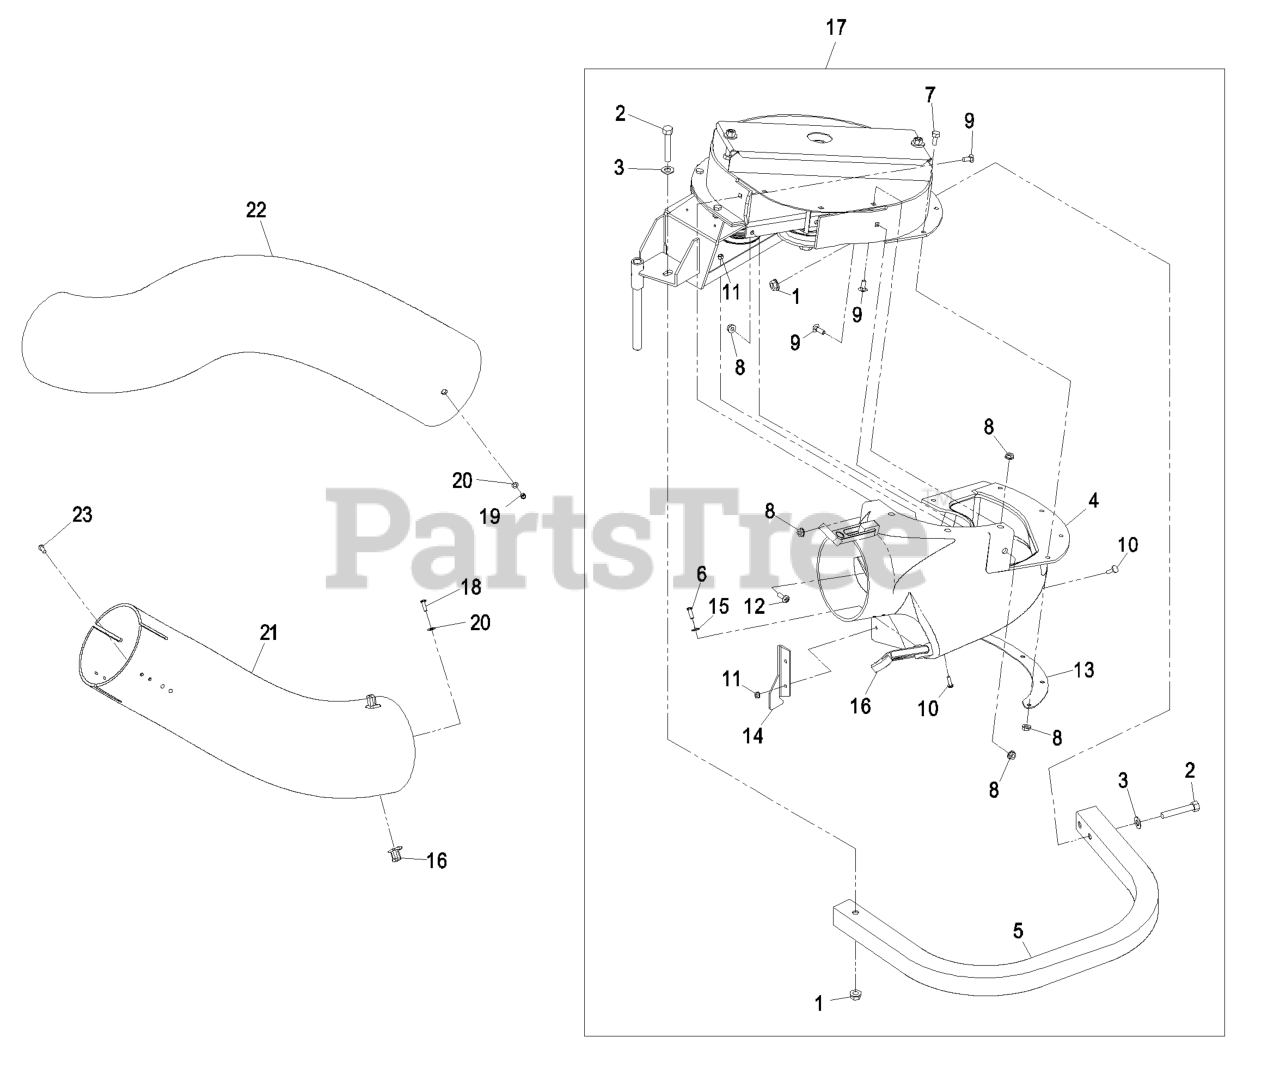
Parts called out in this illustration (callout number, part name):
1	NUT-HHF, WHIZ
2	SCREW-HH
3	WASHER-FLAT
4	ASM,BLOWER CHUTE SMALL
6	SCREW-PPH
7	SCREW-HH
9	SCREW-CARR
10	SCREW-HEAD, TRUSS
13	PLATE-BACKING, BLOWER
14	PLATE, FILLER
15	WASHER-FLAT
16	LATCH DRAW
17	ASM,BLOWER 44/48 - SERVIC
18	SCREW-PPH
19	NUT-LOCK, NI
20	WASHER-FLAT
23	SCREW-HWH
